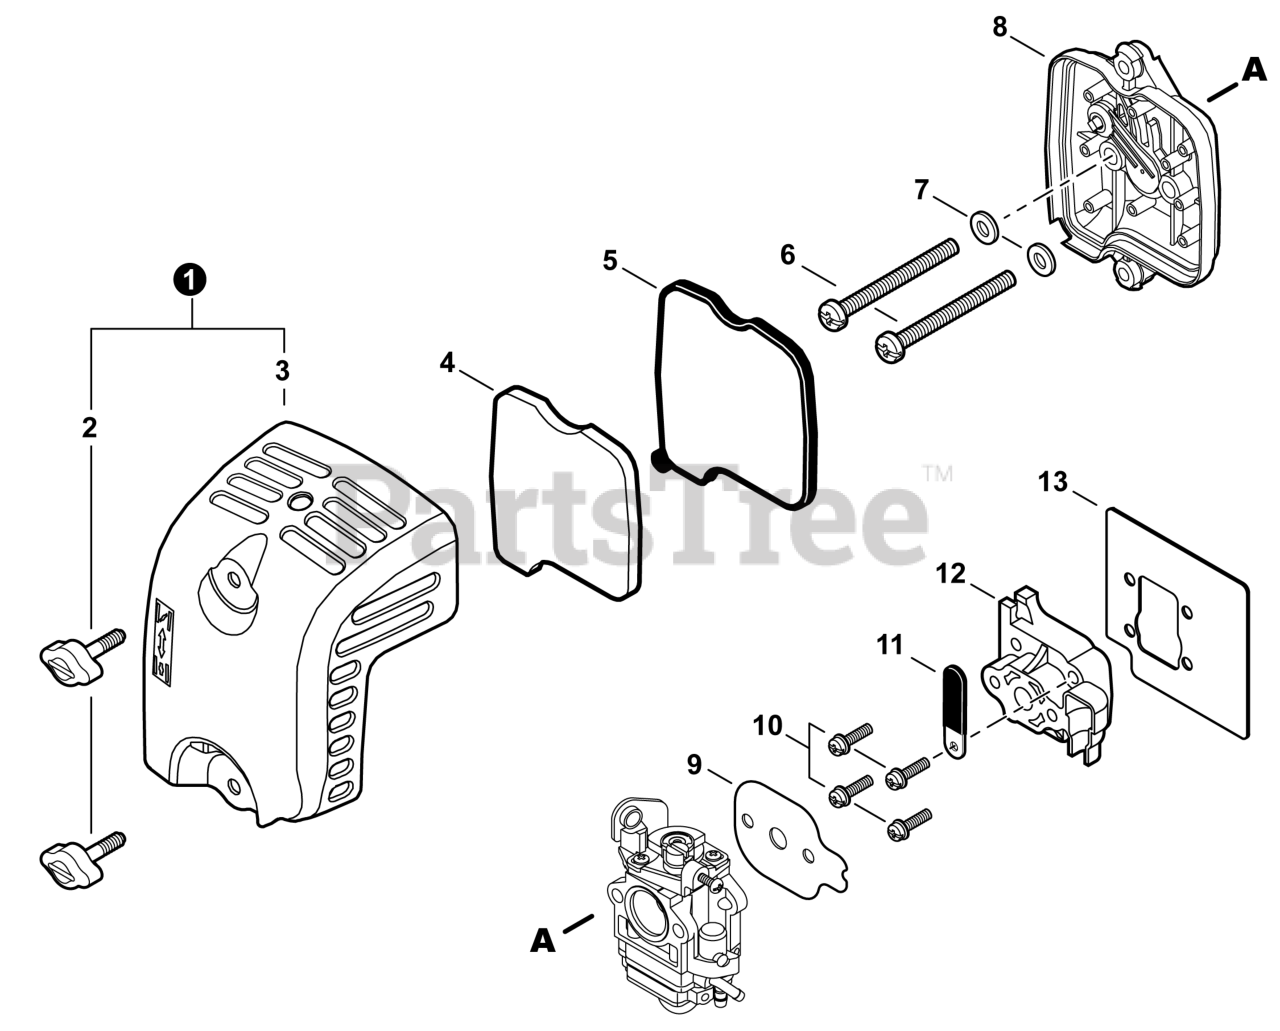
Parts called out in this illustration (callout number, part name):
1	COVER ASSY, AIR FILTER
2	THUMBSCREW
3	COVER, AIR FILTER
4	PRE-FILTER, FOAM
5	FILTER, AIR
6	SCREW M5×60
7	WASHER 5.5×12×0.8
8	CASE, AIR FILTER
9	GASKET, CARBURETOR
10	SCREW M5×25
12	INSULATOR WITH REED VALVE
13	HEAT SHIELD, INTAKE
